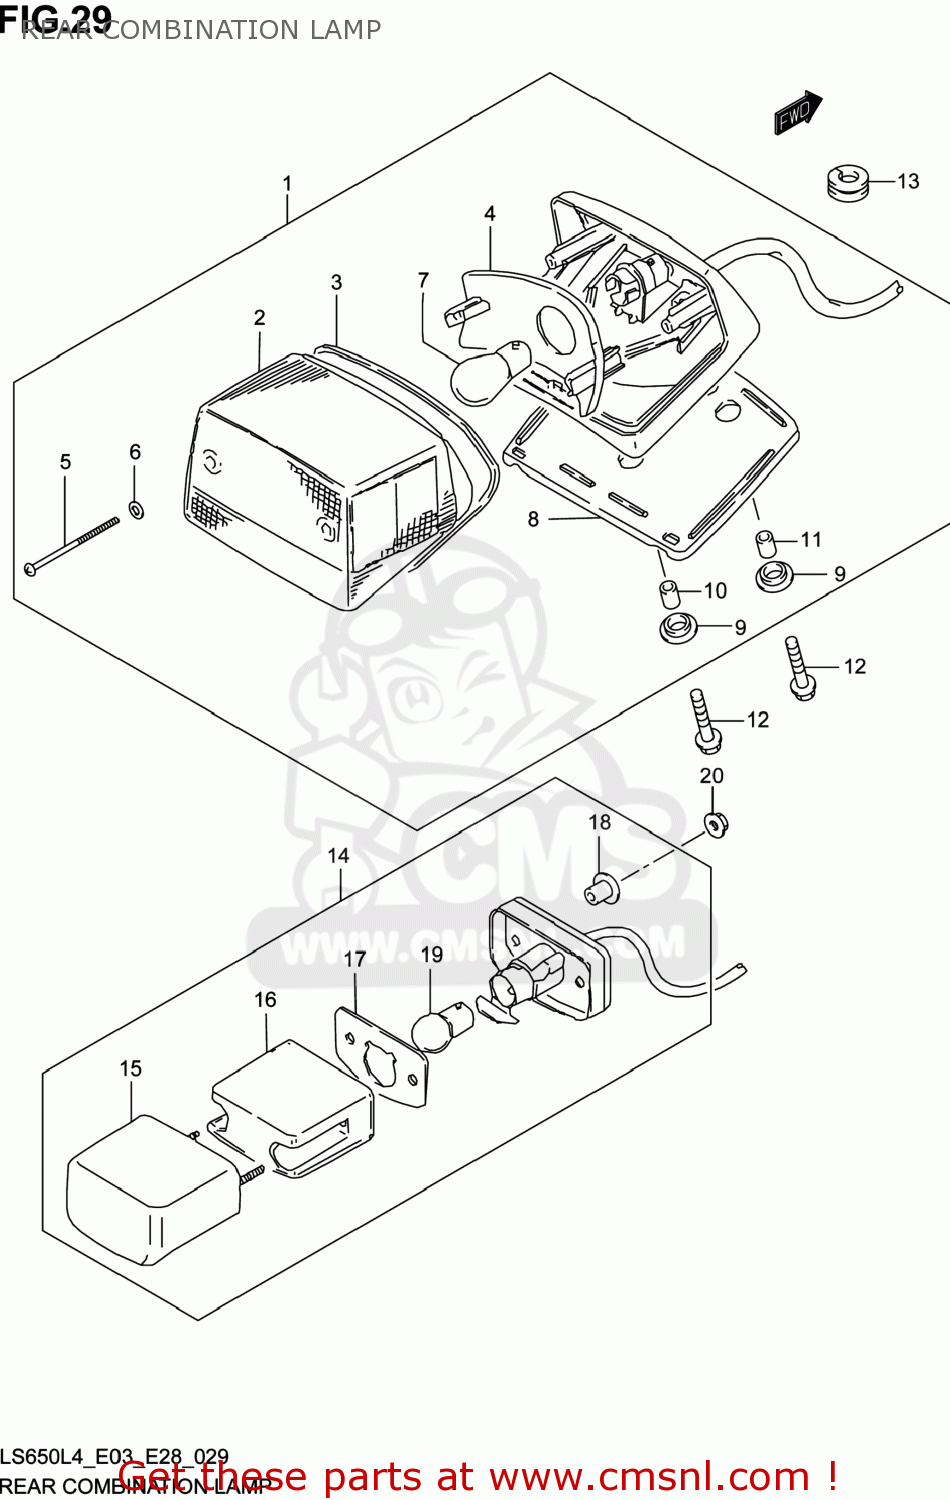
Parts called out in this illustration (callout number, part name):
1	LAMP ASSY,RR COMBINATION
2	LENS
3	GASKET (NAS)
4	REFLECTOR
5	SCREW
6	GASKET (NAS)
7	BULB(12V21/5W,BF141-49642A)
8	CUSHION
9	CUSHION
10	SPACER
11	SPACER
12	BOLT(6X25)
13	GROMMET
14	LAMP ASSY,LICENSE
15	COVER,LENS
16	LENS
17	GASKET,LICENSE LAMP (NAS)
18	SPACER
19	BULB(12V5W,BF150-40160A)
20	NUT
